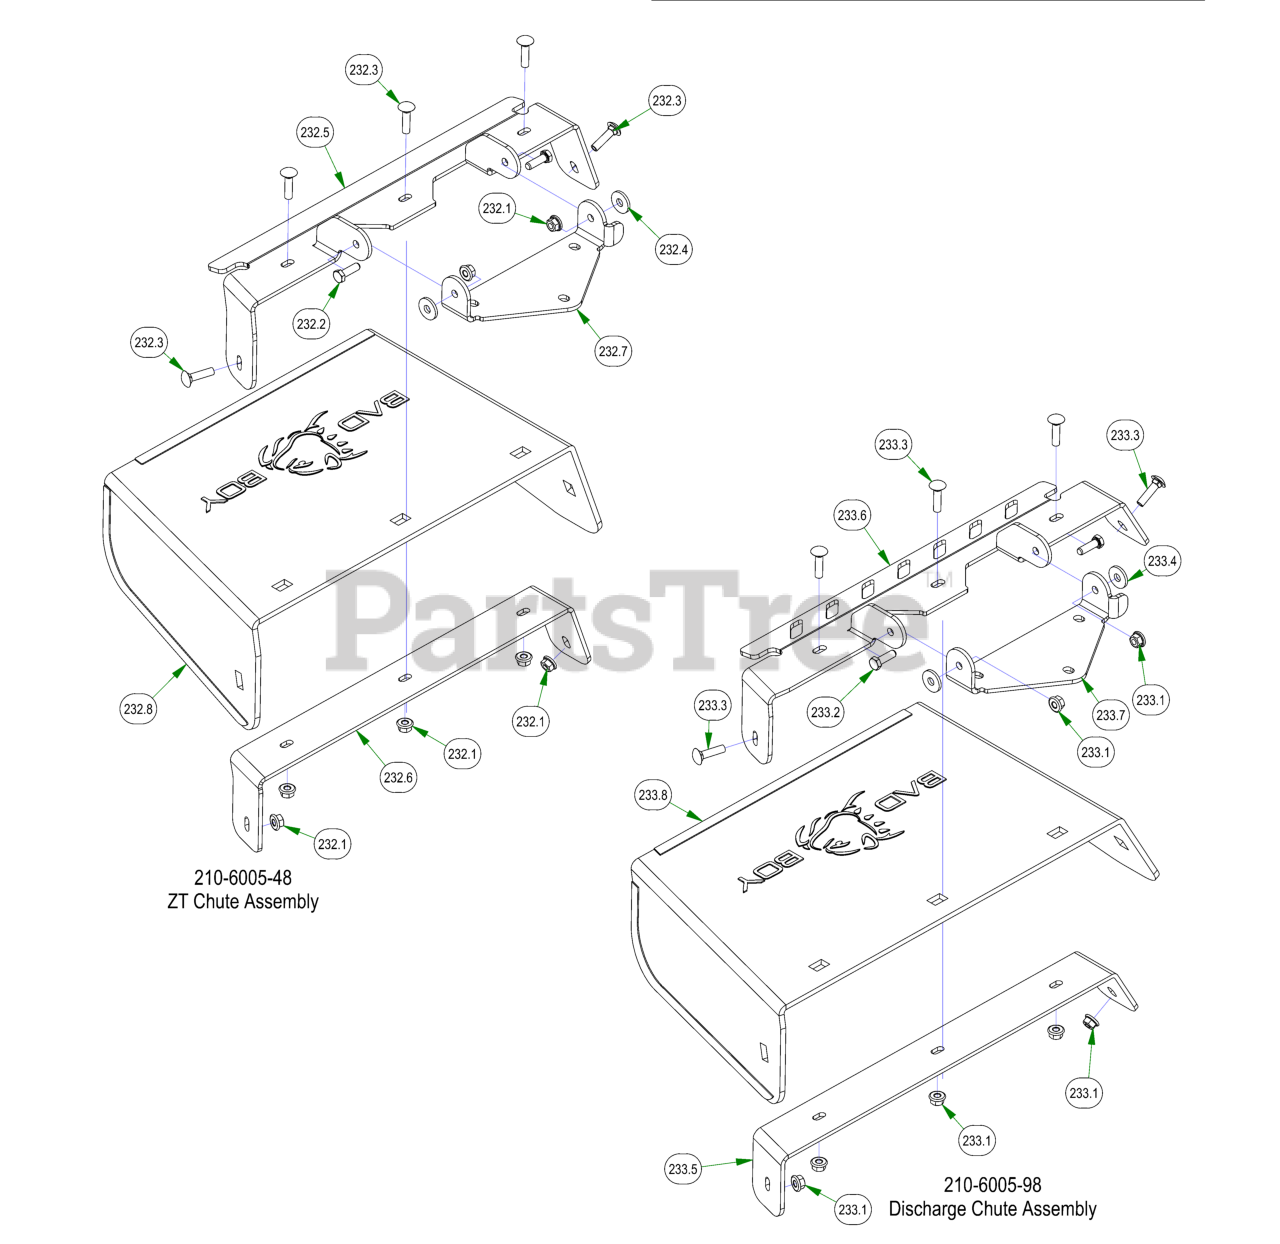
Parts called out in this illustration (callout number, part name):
232	ZT Chute Assembly
232.1	5/16-18 NYLON INSERT FLANGE LOCKNUT ZINC
232.2	5/16-18 X 1 HEX CAP SCREW (GR.5) ZINC
232.3	5/16-18 X 1-1/4 CARRIAGE BOLT ZINC
232.4	.360 ID X .983 OD X .120 THICK FLAT WASHER NYLON
232.5	Discharge Upper Chute Bracket
232.6	Discharge Lower Chute Bracket
232.7	Discharge Chute Hanger (deck mounted)
232.8	Rubber Discharge Chute
233	Discharge Chute Assembly
233.1	5/16-18 NYLON INSERT FLANGE LOCKNUT ZINC
233.2	5/16-18 X 1 HEX CAP SCREW (GR.5) ZINC
233.3	5/16-18 X 1-1/4 CARRIAGE BOLT ZINC
233.4	.360 ID X .983 OD X .120 THICK FLAT WASHER NYLON
233.5	60" Discharge Lower Bracket
233.6	60" Discharge Chute Upper Hanger
233.7	Discharge Chute Hanger (deck mounted)
233.8	Rubber Discharge Chute
